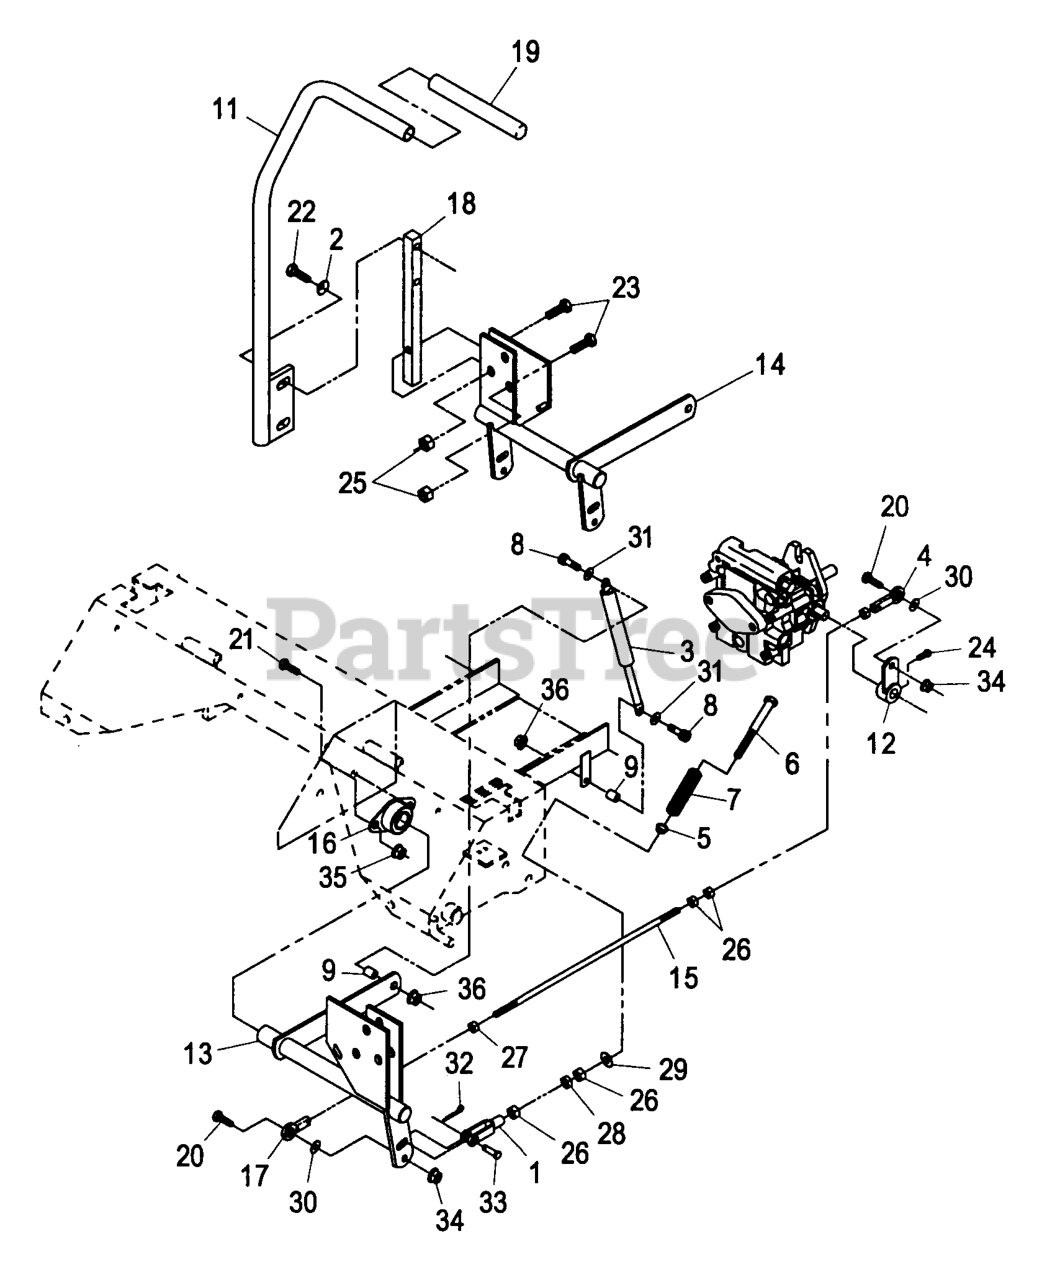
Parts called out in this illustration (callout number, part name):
1	YOKE-ADJUSTABLE
4	BALLJOINT-RH
5	BUSHING-FLANGED
6	BOLT-RETURN, NEUTRAL
7	SPRING-RETURN, NEUTRAL
8	SCREW-HSH
11	ASM,LEVER/GRIP RH
16	BEARING-FLANGE, SIDE
17	BALLJOINT-LH
18	ARM-CONTROL, SHAFT
19	GRIP-CONTROL, MOTION
24	SCREW-SET
33	PIN-CLEVIS
